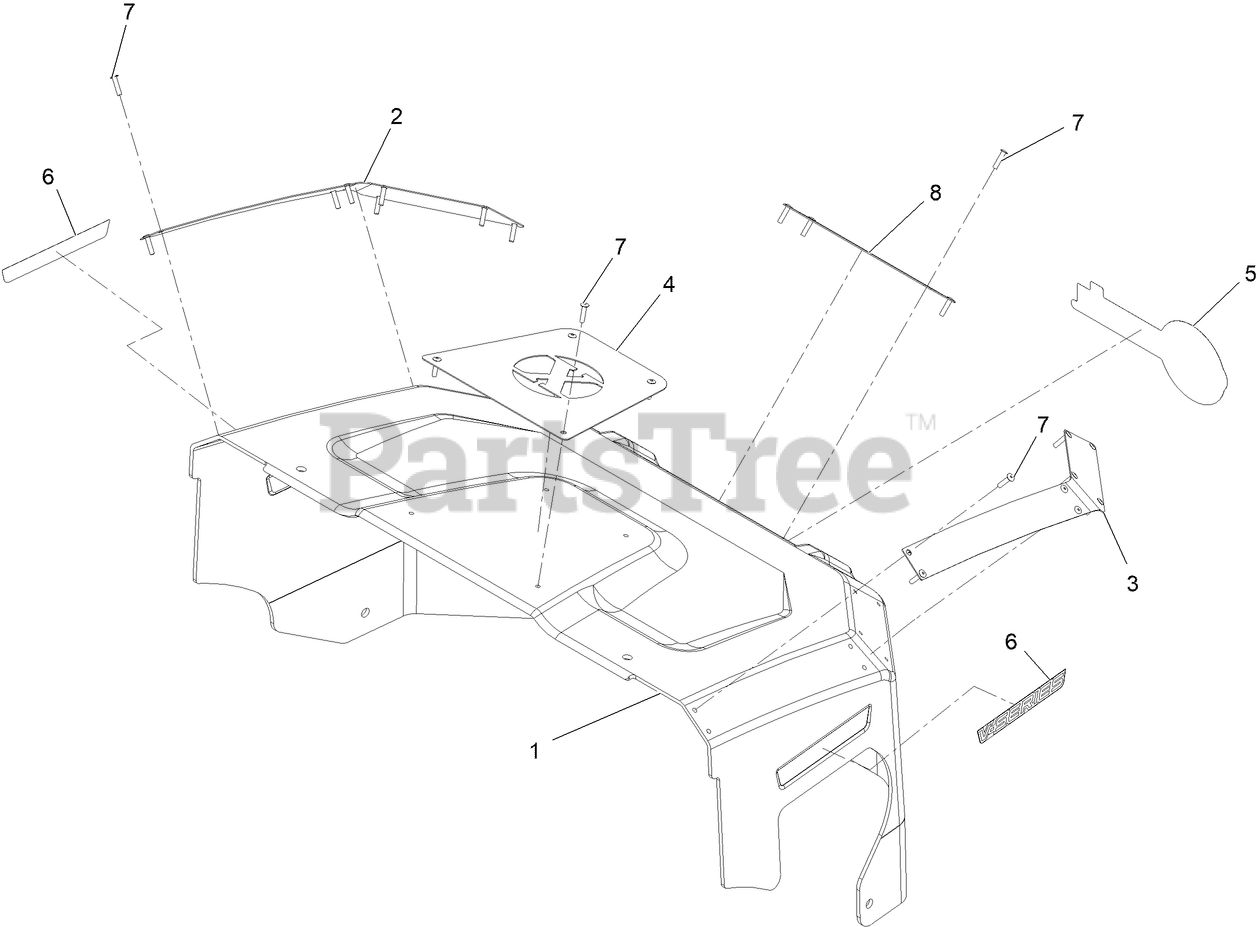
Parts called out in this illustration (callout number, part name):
1	Hood-Rear
2	Trim-Styling, Rt
3	Trim-Styling, Lt
4	PLATE-REAR HOOD ACCENT
5	DECAL-EXMARK LOGO
6	DECAL-V-SERIES
7	RIVET-TRIFOLD
8	Trim-Styling, Rear
